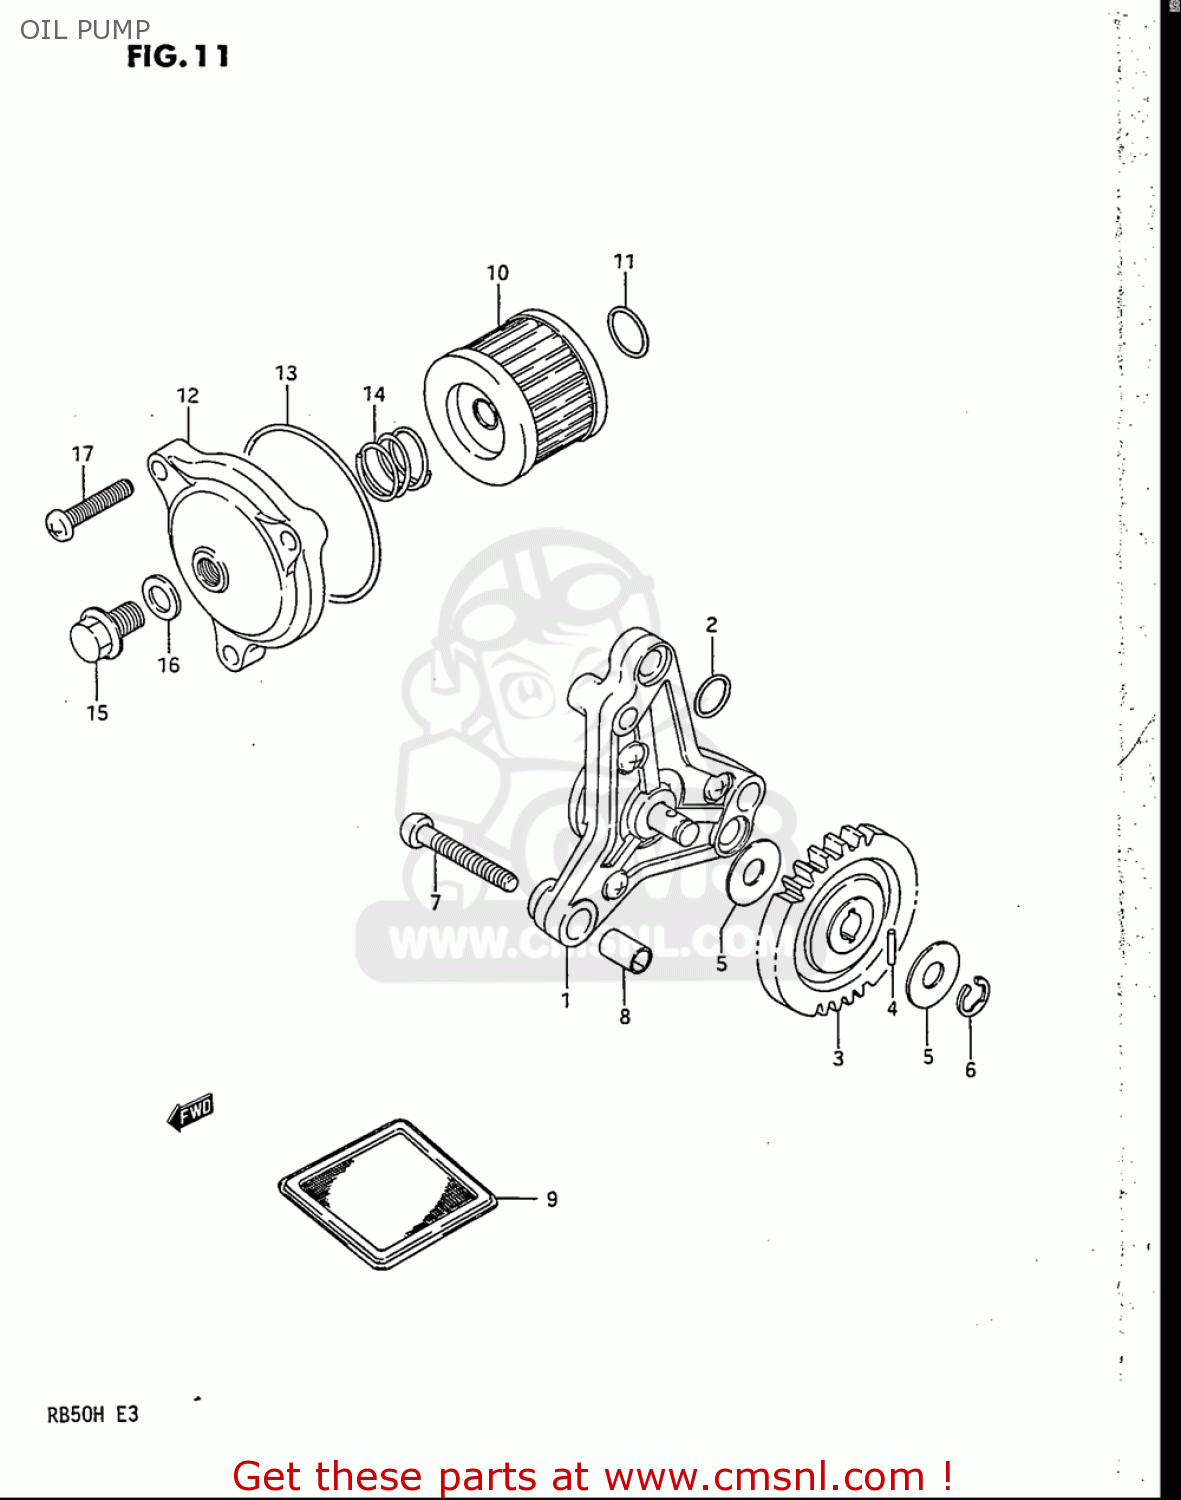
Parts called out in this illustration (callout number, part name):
2	O RING(D:1.9,ID:9.8)
3	GEAR,OIL PUMP DRIVEN (N
4	PIN(2.5X11.8)
5	WASHER
6	E RING
7	SCREW
8	PIN
9	STRAINER,ENGINE OIL
10	FILTER ASSY,ENGINE OIL
11	O RING(D:1.9,ID:13)
12	CAP,OIL FILTER
13	O RING(D:2.4,ID:52.6)
14	SPRING
15	BOLT
16	GASKET(8.2X14X1).6 (NAS)
17	SCREW
